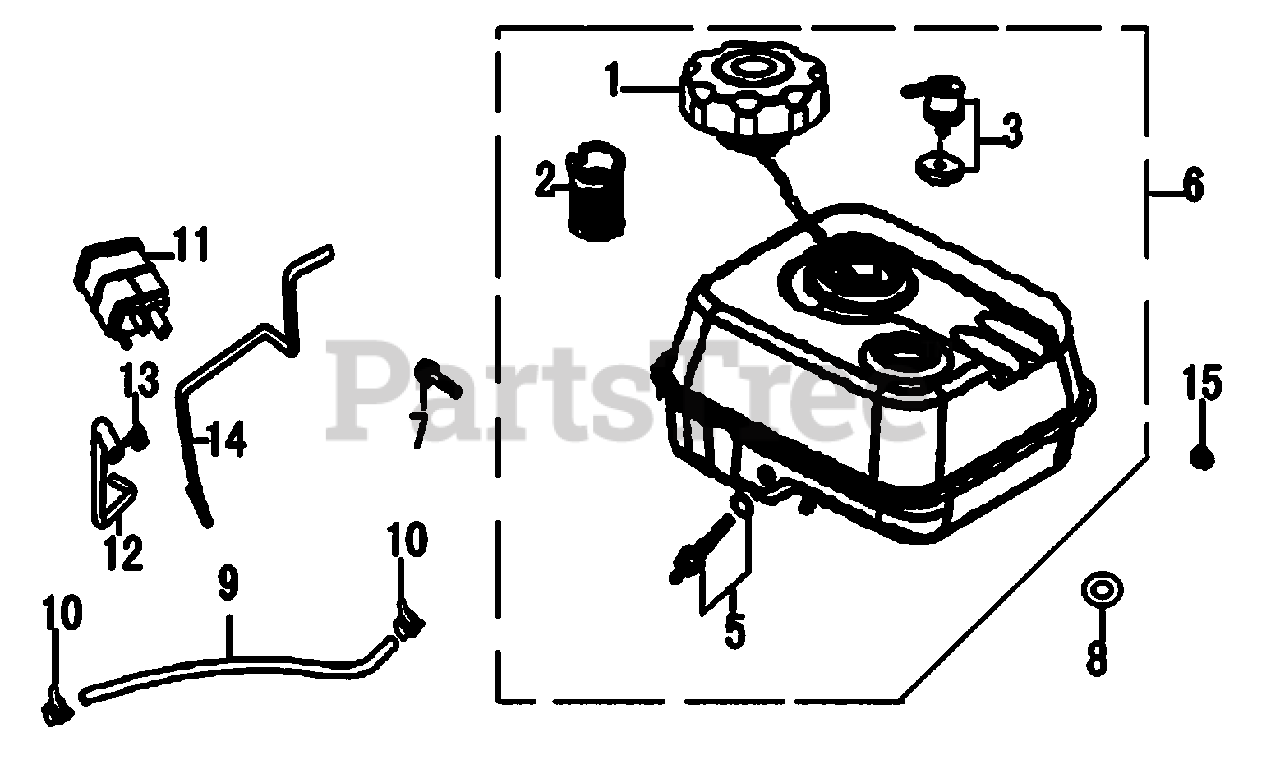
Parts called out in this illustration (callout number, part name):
1	CAP, FUEL
2	FILTER, FUEL
3	ROLL OVER VALVE
5	JOINT ASSY.,FUEL TANK
6	ASSY, FUEL TANK W/ROV
7	BOLT, FLANGE 6X25
8	WASHER, RUBBER
9	HOSE, FUEL(TUBE)
10	CLAMP/COLLAR
11	CARBON CANISTER ASSY
12	HOSE,AIRCLNR TO CARBONCANISTER
14	HOSE, ROV TO CARBON CANISTER
15	NUT, FLANGE 6MM
